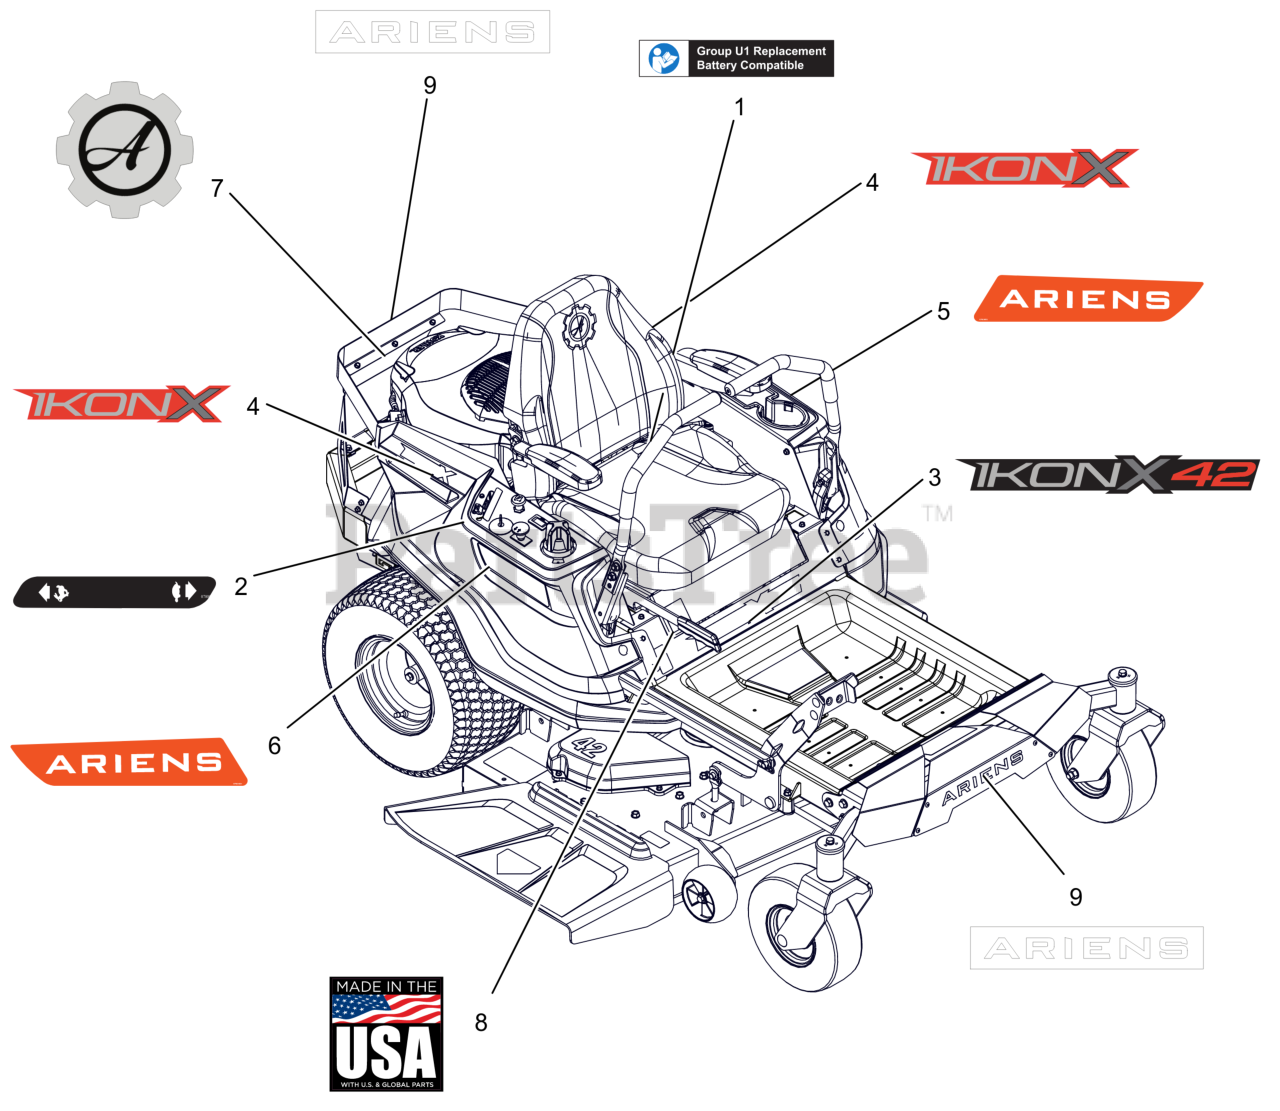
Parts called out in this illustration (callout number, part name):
1	DECAL, U1 BATTERY REPLACEMENT
2	DECAL, DASH DECAL
3	DECAL, IKON-X 42"
4	DECAL, IKON
5	DECAL, FENDER LH
6	DECAL, FENDER RH
7	DECAL, ARIENS-GEAR BADGE -THK
8	DECAL, MADE IN USA
9	DECAL - ARIENS 9.625"
